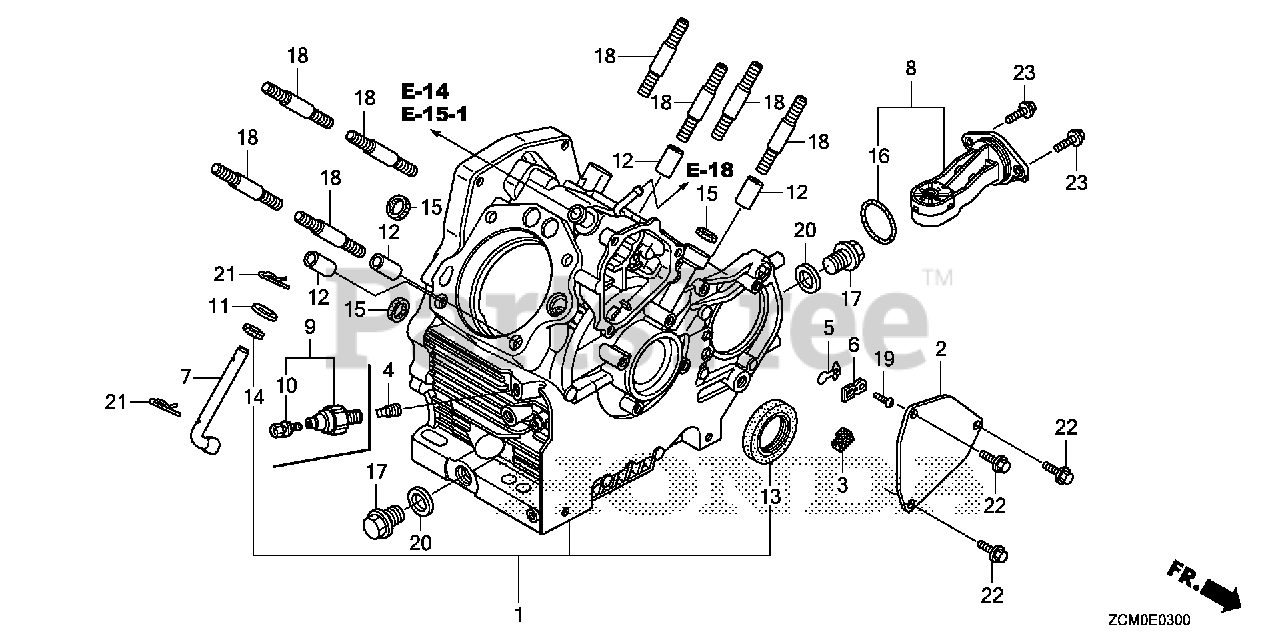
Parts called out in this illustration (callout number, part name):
1	CRANKCASE ASSY.
2	COVER, BREATHER
3	FILTER, BREATHER
4	BOLT, SEALING
5	VALVE, OIL OUTLET
6	PLATE, STOPPER
7	SHAFT, GOVERNOR ARM
8	SWITCH ASSY., OIL LEVEL
11	WASHER, PLAIN (10MM)
12	PIN, DOWEL (12X20)
13	OIL SEAL (38X58X9)
14	OIL SEAL (10X16X5)
15	GASKET, OIL PASSAGE
16	O-RING (37.9X2.4)
17	BOLT, DRAIN PLUG (20MM)
18	BOLT, STUD (10X40)
19	SCREW, PAN (3X8)
20	WASHER, DRAIN PLUG (20MM)
21	PIN, LOCK (10MM)
22	BOLT, FLANGE (6X14)
23	BOLT, FLANGE (6X16)
